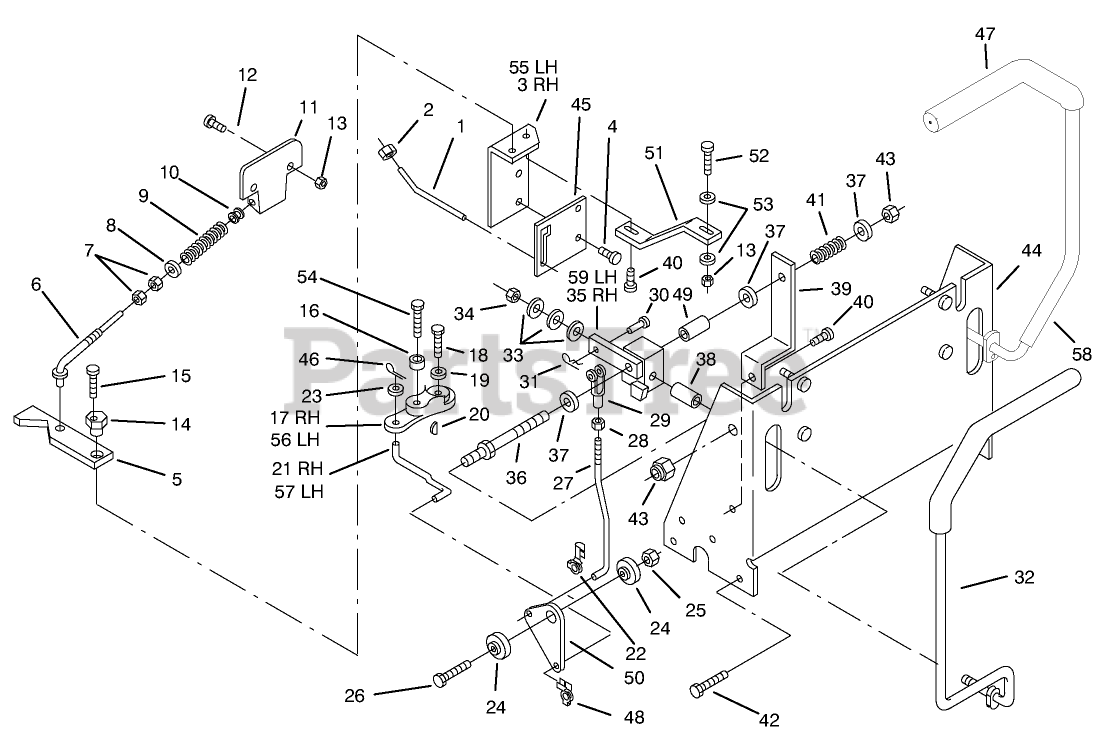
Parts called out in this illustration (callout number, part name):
1	LEVER-TOW VALVE
2	NUT-LOCK, NI
3	Bracket-Arm
4	SCREW-TAPTITE
5	ARM-HYDRO NEUTRAL
6	ROD-NEUTRAL RETURN
7	NUT-JAM
8	WASHER-FLAT
9	SPRING COMPRESSION
10	NYLINER BUSHING
11	BRKT-ROD SUPPORT
12	SCREW-HSH
13	NUT-LOCK, NI
16	SPACER
17	ARM-SPEED CTRL RH
18	Bolt
19	WASHER-FLAT
20	KEY WOODR 1/8X1/2 DI
21	LINK-R.H.
22	CLIP-CLEVIS L.H.
23	WASHER-FLAT
24	SPACER-CLUTCH LINK
25	NUT-LOCK, NI
26	SCREW-HH
27	ROD-HYDRO CTRL. ADJ.
28	NUT-JAM
30	PIN-CLEVIS
31	Pin-Cotter
32	Lever-Steering RH
33	SPRING-BELLVILLE
34	NUT-LOCK, NI
35	Lever-Pivot RH
36	SHAFT-PIVOT
37	WASHER-FLAT
38	BUSHING-STR LVR PVT
39	BRACKET-RETAINER
40	SCREW-HWHTF
41	SPRING
42	SCREW-HWH, TAPTITE
43	NUT-LOCK, NI
44	WLDMT-LEVER SUPPO
45	Plate-Valve
46	PIN-COTTER
47	GRIP - CUSHION
48	CLIP-CLEVIS R.H.
49	BUSHING
50	Plate-Pivot
51	Bracket-Support
52	SCREW-HH
53	WASHER-PLAIN
54	SCREW-HH
55	Bracket-Arm
56	ARM-SPEED CTRL LH
57	LINK-L.H.
58	Lever-Steering LH
59	Lever-Pivot LH
